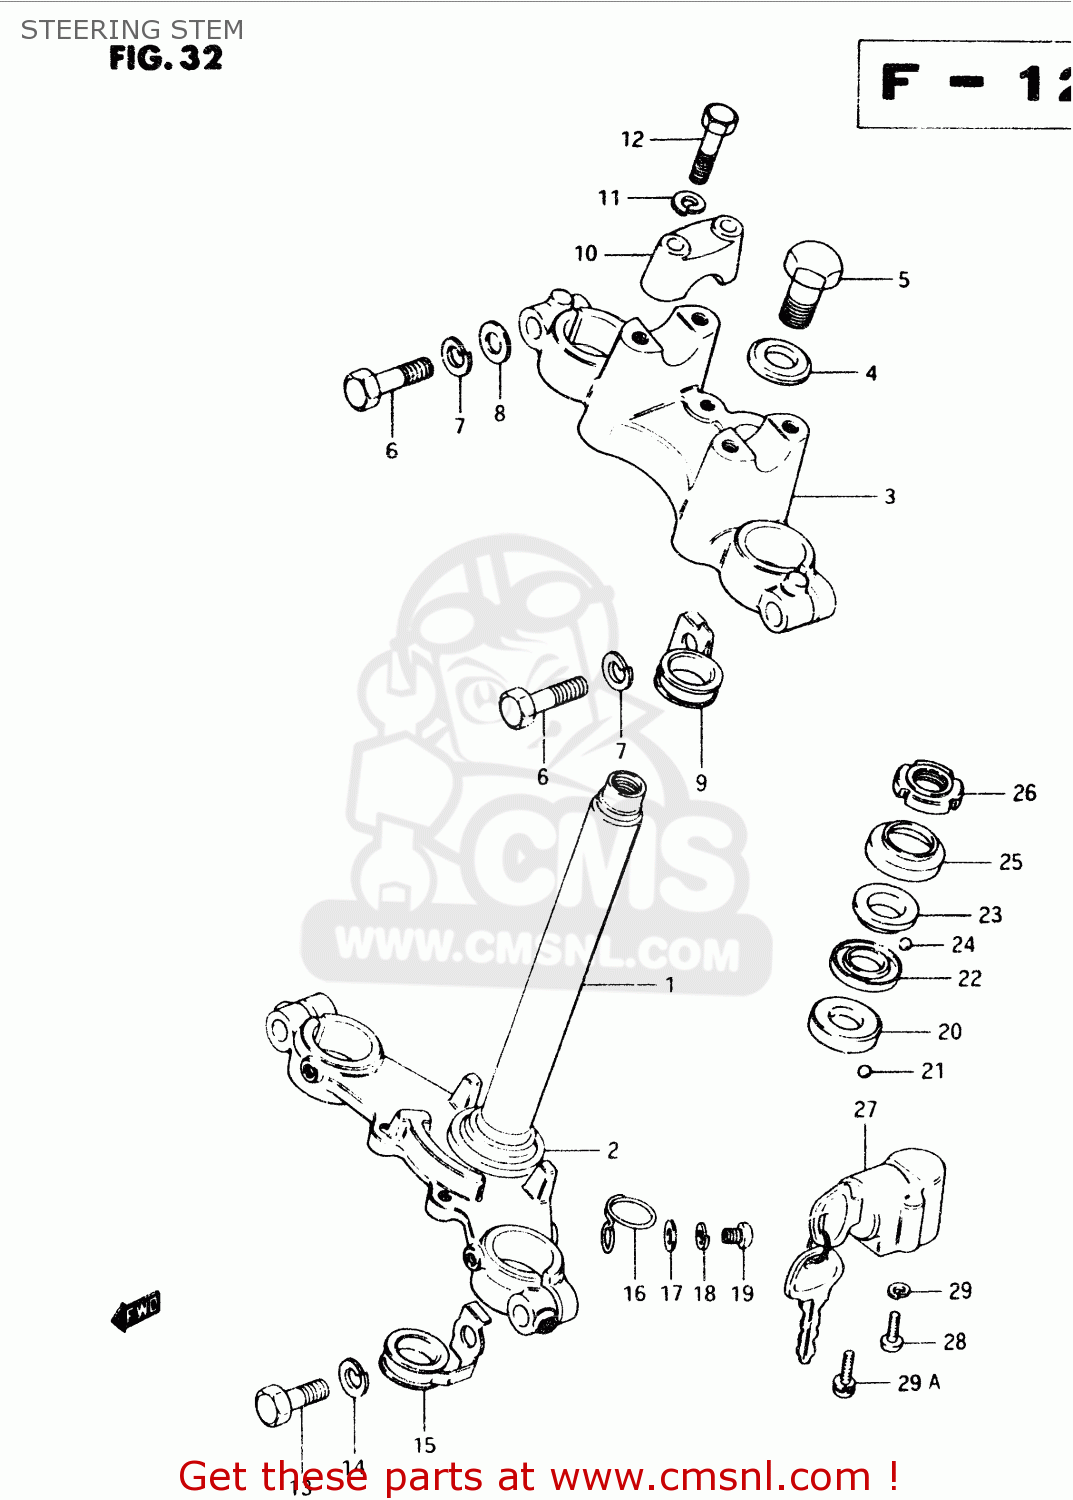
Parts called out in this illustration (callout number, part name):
1	STEM, STEERING (PEARL)
2	RACE,STEERING OUTER LWR
3	HEAD,STEERING STEM
4	WASHER (10.5X30X2.3)
5	BOLT,STEERING STEM HEAD
6	BOLT
7	WASHER,LOCK,10
8	WASHER
9	CLIP
10	HOLDER,HANDLEBAR
11	LOCK WASHER
12	BOLT
13	BOLT,M10X1.25X
14	WASHER,LOCK,10
15	CLIP
16	CLIP
17	WASHER
18	WASHER,LOCK
19	SCREW 6X12
20	LACE,STEERING INNER LWR
21	BALL
22	RACE,STEERING INNER UPR
23	RACE,STEERING OUTER UPR
24	BALL
25	DUST SEAL,STEERING UPR
26	NUT,STEERING STEM(25X44X10)
27	LOCK ASSY,STEERING
28	SCREW
29	LOCK WASHER
29A	SCREW
